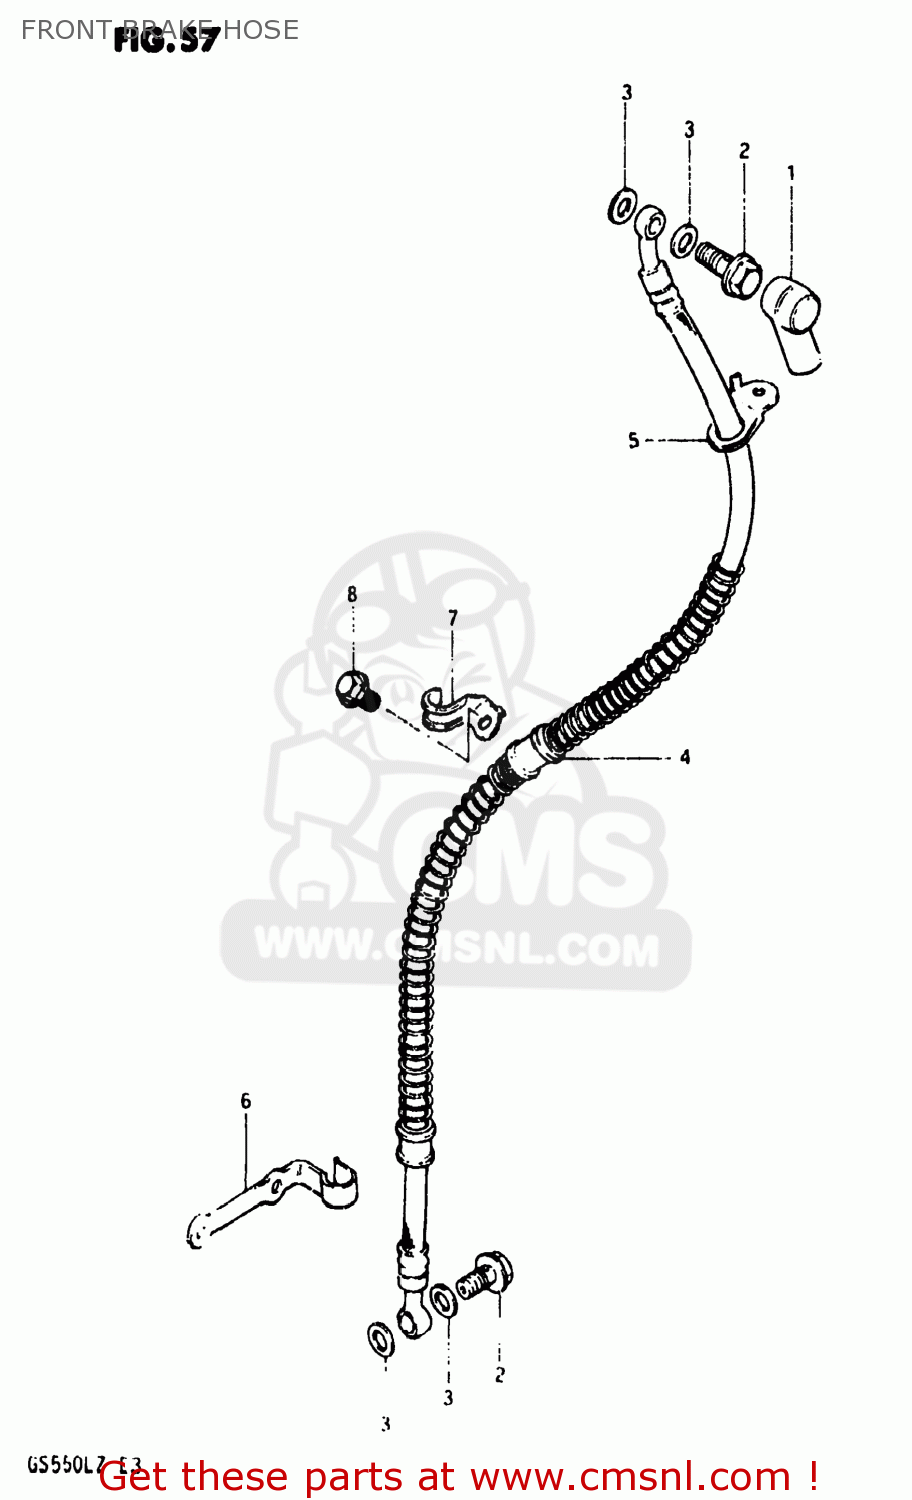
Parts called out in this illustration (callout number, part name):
1	BOOT,MASTER CYLINDER
2	BOLT,UNION
3	WASHER
4	HOSE,FRONT BRAKE
5	GUIDE,BRAKE HOSE NO.1
6	GUIDE,BRAKE HOSE NO.2
7	GUIDE,BRAKE HOSE NO.3
8	BOLT
